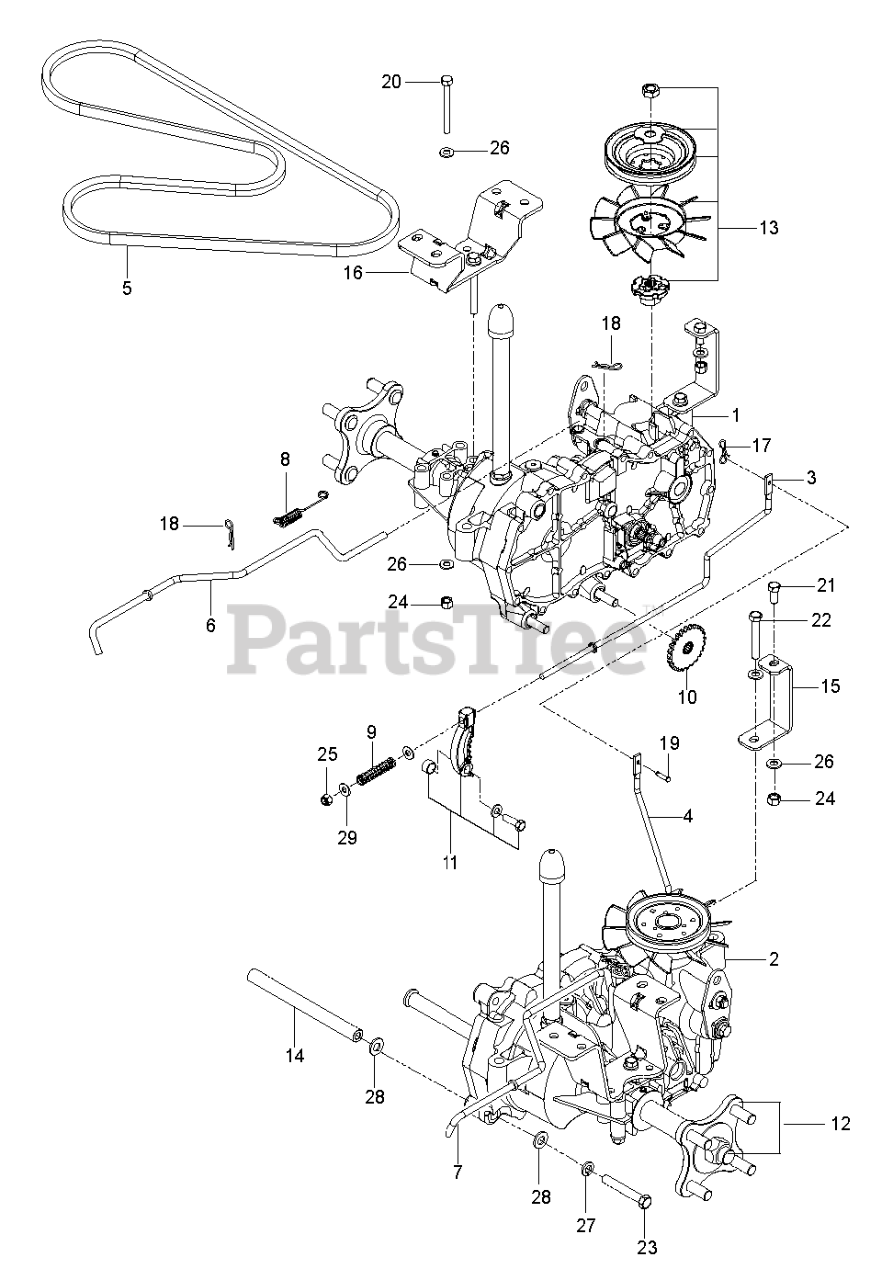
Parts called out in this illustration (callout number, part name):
1	HG_EZT, LT
2	HG_EZT, RT
3	LINKAGE.BRAKE.LT
4	LINKAGE, BRAKE RT
5	BELT, HYDRO PUMP
6	ROD.BYPASS.RZ.LH
7	ROD.BYPASS.RHT
8	SPRING.ROD.BYPASS.EZT
10	HG_DISC COG BRAKE 51635
11	HG_KIT BRAKE ARM (EZT)
12	HG_KIT, HYDRO-GEAR HUB
13	KIT FAN/PULLEY 72137
14	SPACER TUBE EZT
15	SUPPORT.FRONT.TRANS.PNTX431
16	BRACKET.EZT.MOUNT.REAR.PNTX431
17	PIN COTTER;LOCKING;BOWTIE;1IN
18	HAIRPIN #2
19	PIN.CLEVIS.3/16X.475
21	HCS 5/16C X 3/4
22	BOLT.FIN HEX 5/16-18UNC X2 1/4
23	HCS 3/8C X 2 1/2
24	NUT.71038.31-18.HEX.NYLOCK
25	NUT.1/4-20.HEX.NYLOC.ZD
26	WASHER
27	SLW 3/8 STD
28	WASHER
